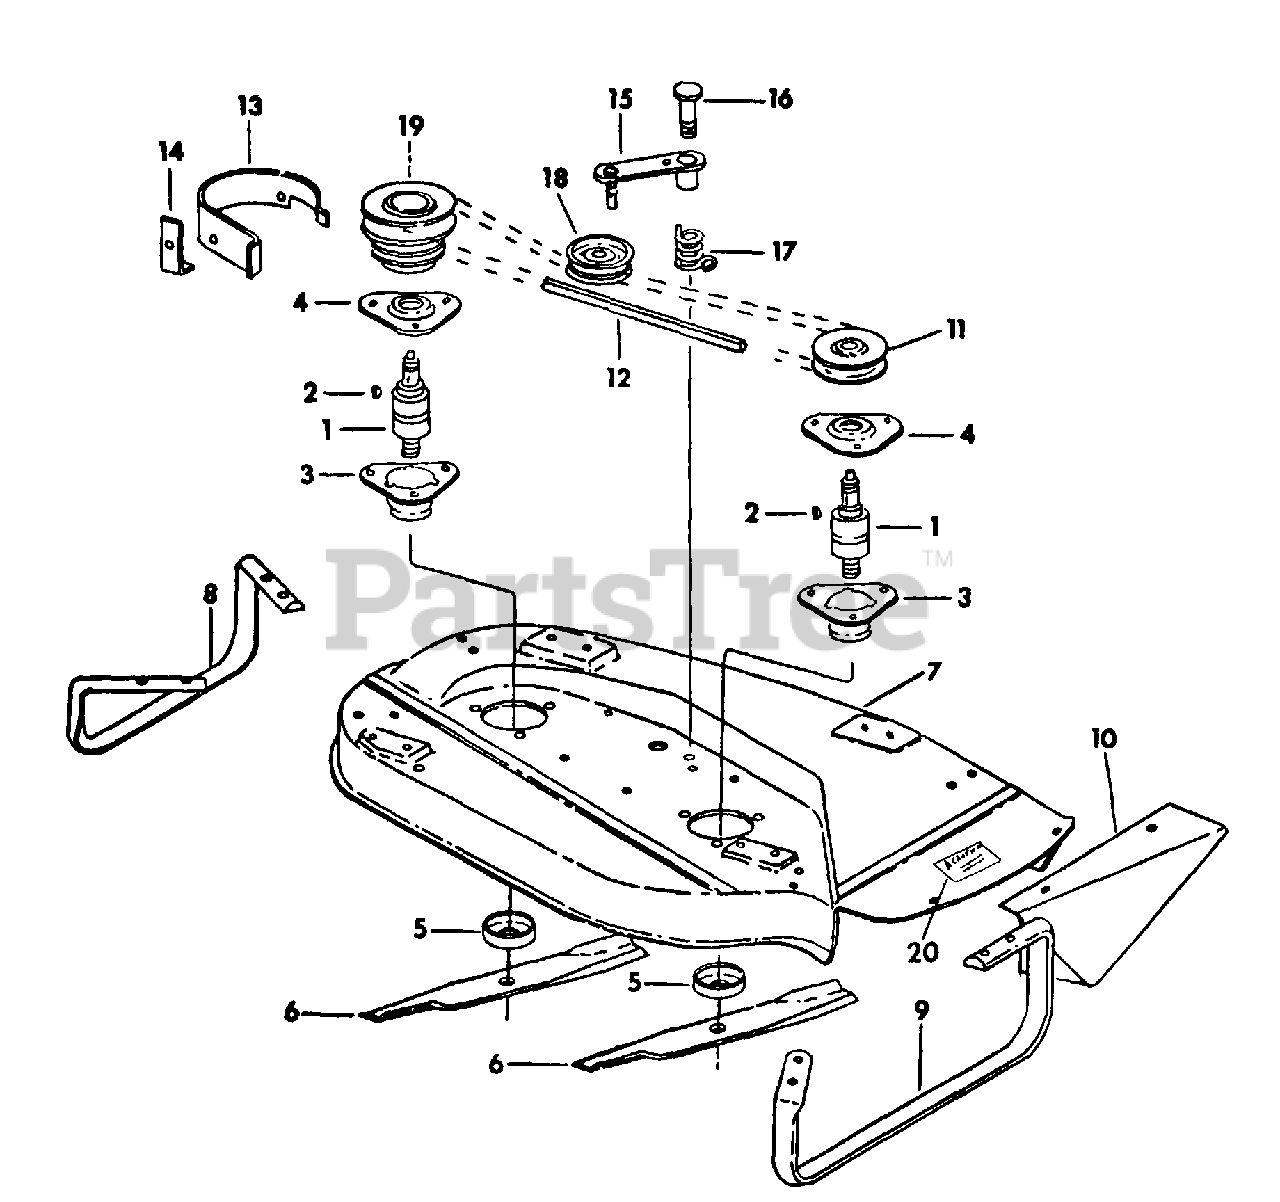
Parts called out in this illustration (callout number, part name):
1	BEARING, BALL AND FAN TYPE
2	KEY, 1/4 X 3/4 WOODRUFF
3	HOUSING, SPINDLE
4	CAP, SPINDLE HOUSING
5	CUP, SPINDLE
6	BLADE, 32 IN -COATED EDGE-
6	BLADE 32 IN
7	HOUSING W/PRODUCT GRAPHIC, IH-57801-C2, 32 IN. MOWER
8	RUNNER, LH MOWER
9	RUNNER, RH MOWER
10	SHIELD, DEFLECTOR 32 IN
11	PULLEY, BLADE
12	BELT, BLADE DRIVE
13	SHIELD, BELT GUIDE
14	BRACKET, BELT GUIDE
15	ARM ASSY, IDLER
16	BOLT, IDLER ARM PIVOT
17	SPRING, TORSION
18	PULLEY, IDLER
19	PULLEY, LH SPINDLE
20	PRODUCT GRAPHIC, CAUTION
